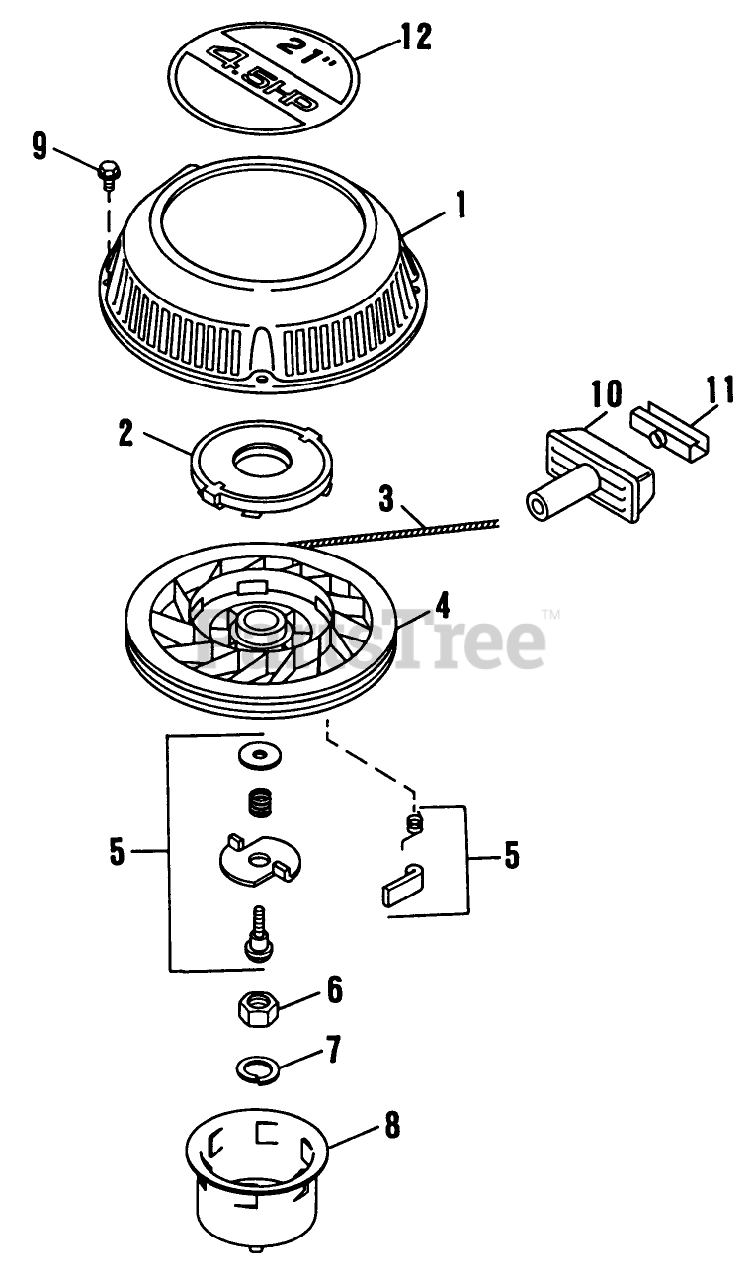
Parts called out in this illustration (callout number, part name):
4	PULLEY
5	DOG KIT
6	NUT
8	HUB STARTER SM
9	SCREW SEMS SM
11	CLIP-STARTER
